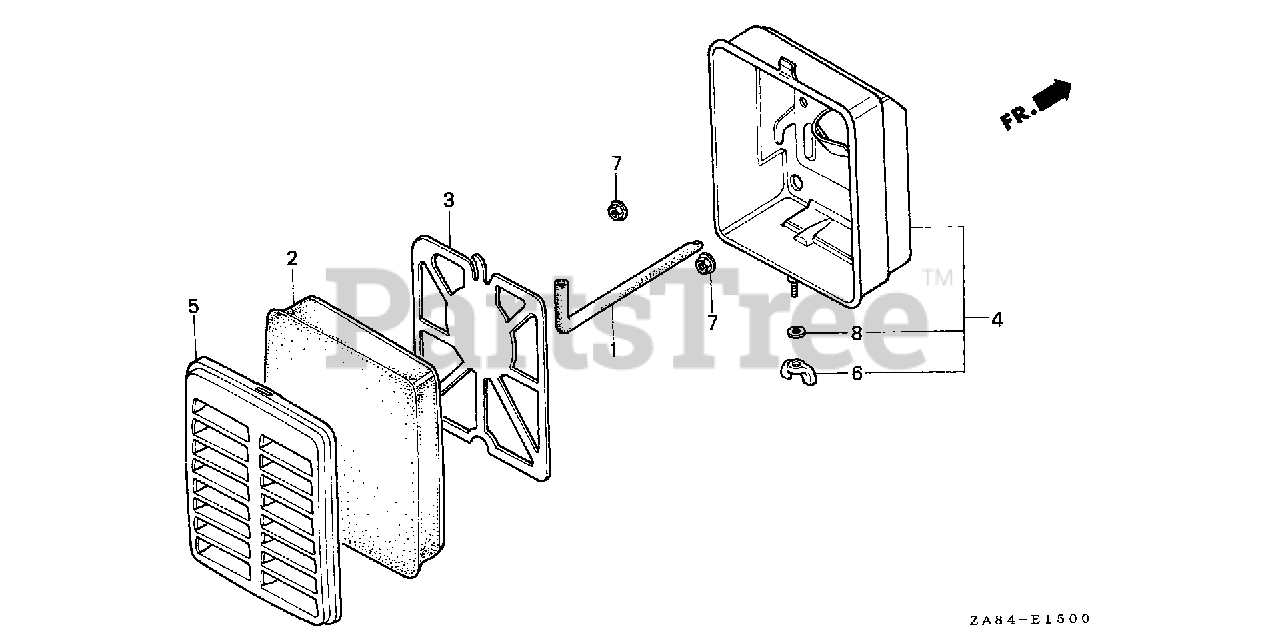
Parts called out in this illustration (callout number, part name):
1	TUBE, BREATHER
2	ELEMENT, AIR CLEANER
3	GRID, AIR CLEANER
4	HOUSING, AIR CLEANER
5	COVER, AIR CLEANER
6	WINGNUT, TOOL BOX SETTING
7	NUT, FLANGE (5MM)
8	WASHER, PLAIN (6MM)
